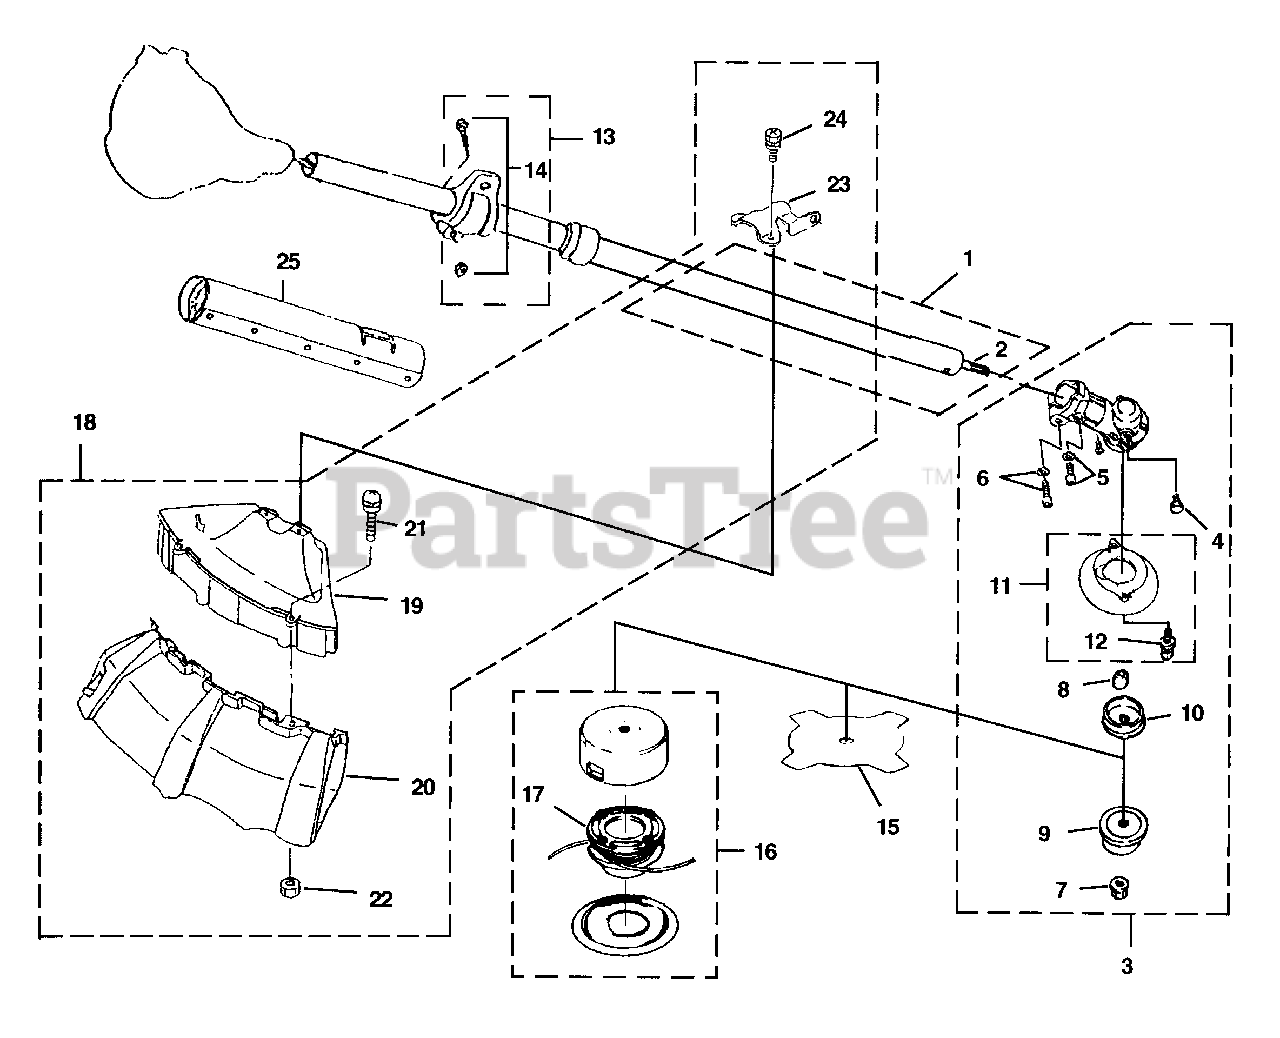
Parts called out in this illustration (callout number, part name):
1	DRIVESHAFT HOUSING
2	DRIVESHAFT
3	GEAR HEAD
4	BOLT-Grease
5	BOLT ASSEMBLY (M5 X 12 SW)
6	BOLT ASSEMBLY (M5X 25 SW)
7	NUT
9	WASHER-Cupped
10	WASHER-Flange
11	GRASS GUARD
12	SCREW-Socket Hd (M5 x 12 W SW)
13	HANGER ASSEMBLY
14	SCREW AND NUT
15	BLADE CUTTER
16	STRINGHEAD ASSEMBLY (.095)
17	SPOOL & STRING (.095)
18	PROTECTOR ASSEMBLY
19	PROTECTOR COMPLETE
20	PROTECTOR COMPLETE
21	SCREW ASSEMBLY
23	CLAMP-Protector
24	BOLT ASSEMBLY
